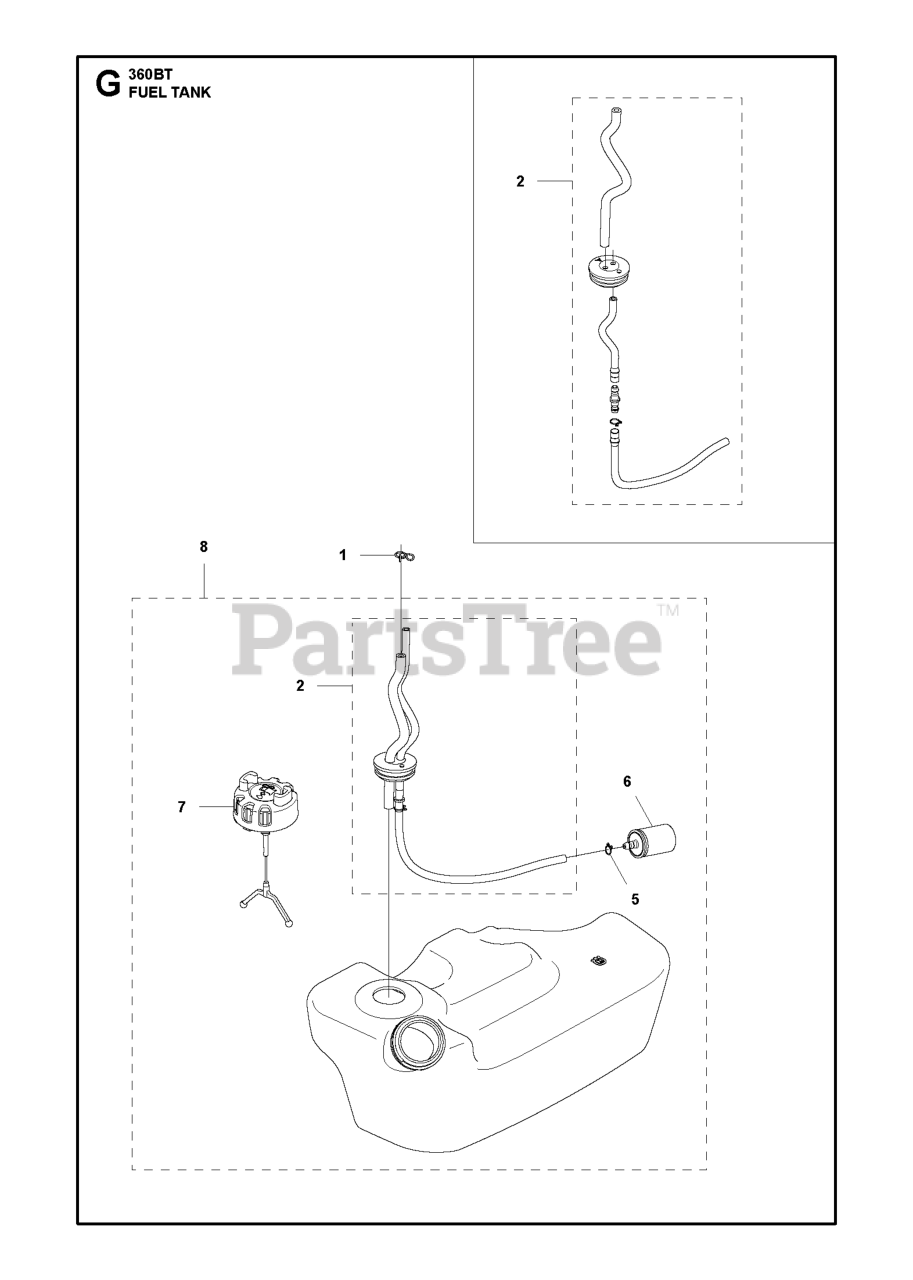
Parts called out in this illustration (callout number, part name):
2	HOSE ASSY EVP
6	FILTER ASSY
7	FUEL CAP ASSY
8	FUEL TANK ASSY
8	ASSY TANK EVP
